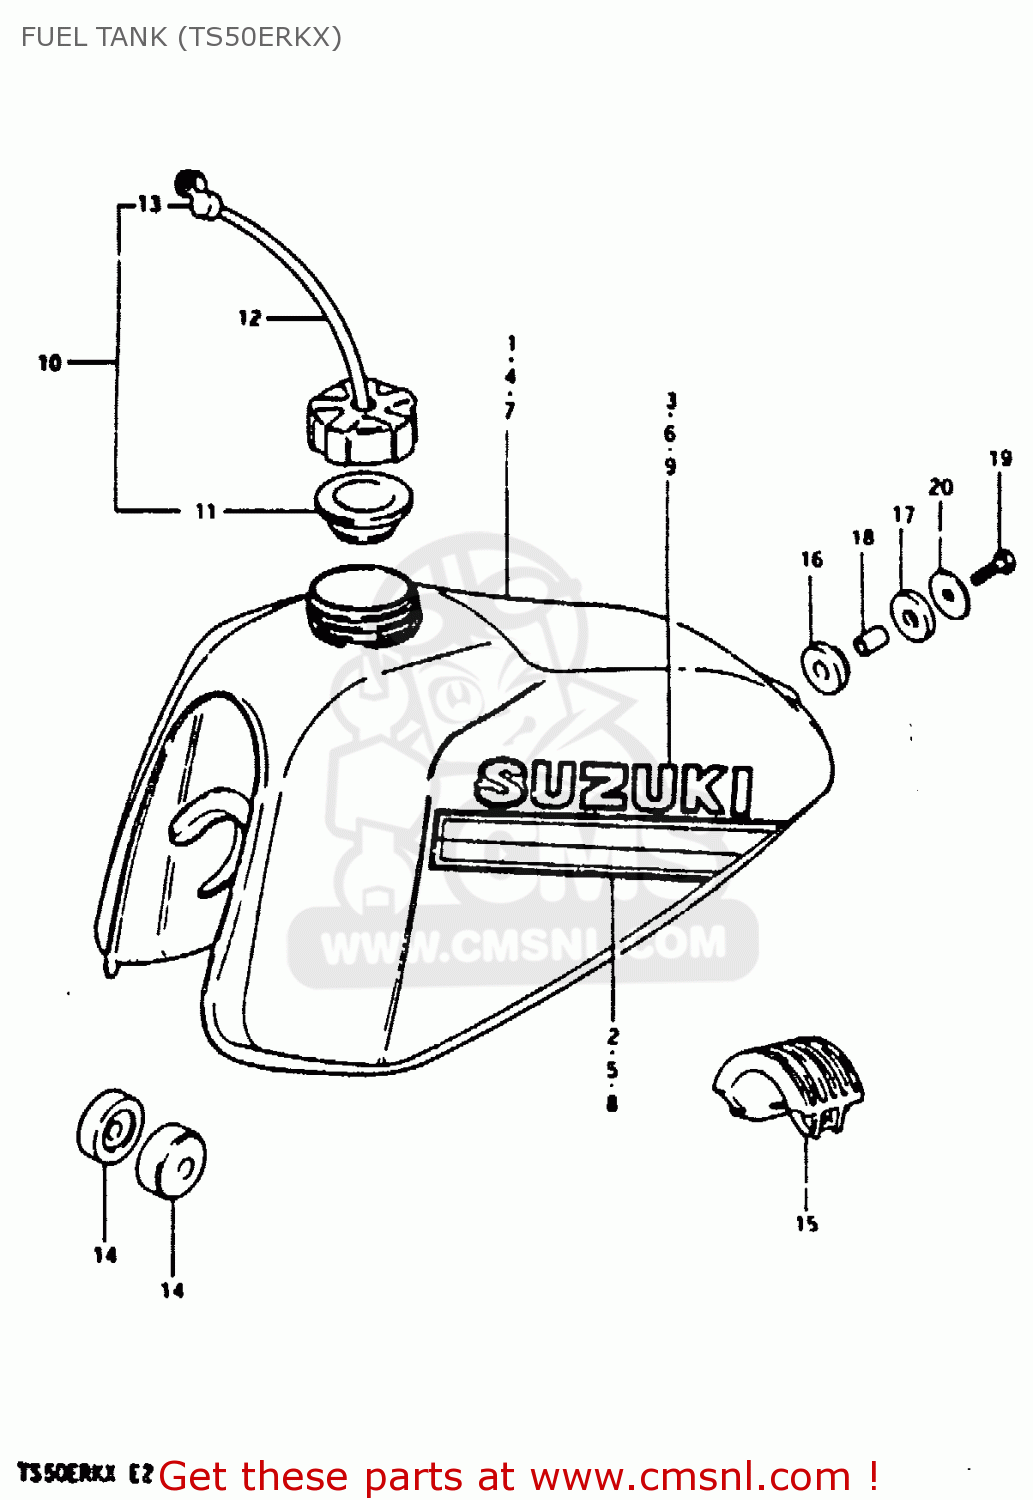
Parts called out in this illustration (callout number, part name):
1	TANK, FUEL (RED)
2	TAPE SET
3	EMBLEM
4	TANK, FUEL (BLUE)
5	TAPE SET
6	EMBLEM
7	TANK, FUEL (WHITE)
8	TAPE SET
9	EMBLEM(BLACK)
10	CAP SET,FUEL TANK
11	GASKET,FUEL TANK CAP (NAS)
12	HOSE
13	CLAMP,FUEL TANK BREATHER HOSE
14	CUSHION
15	CUSHION,FUEL TANK
16	CUSHION
17	CUSHION
18	SPACER(8.5X12X19)
19	BOLT (8X30)
20	WASHER (8.5X29X1.6)
